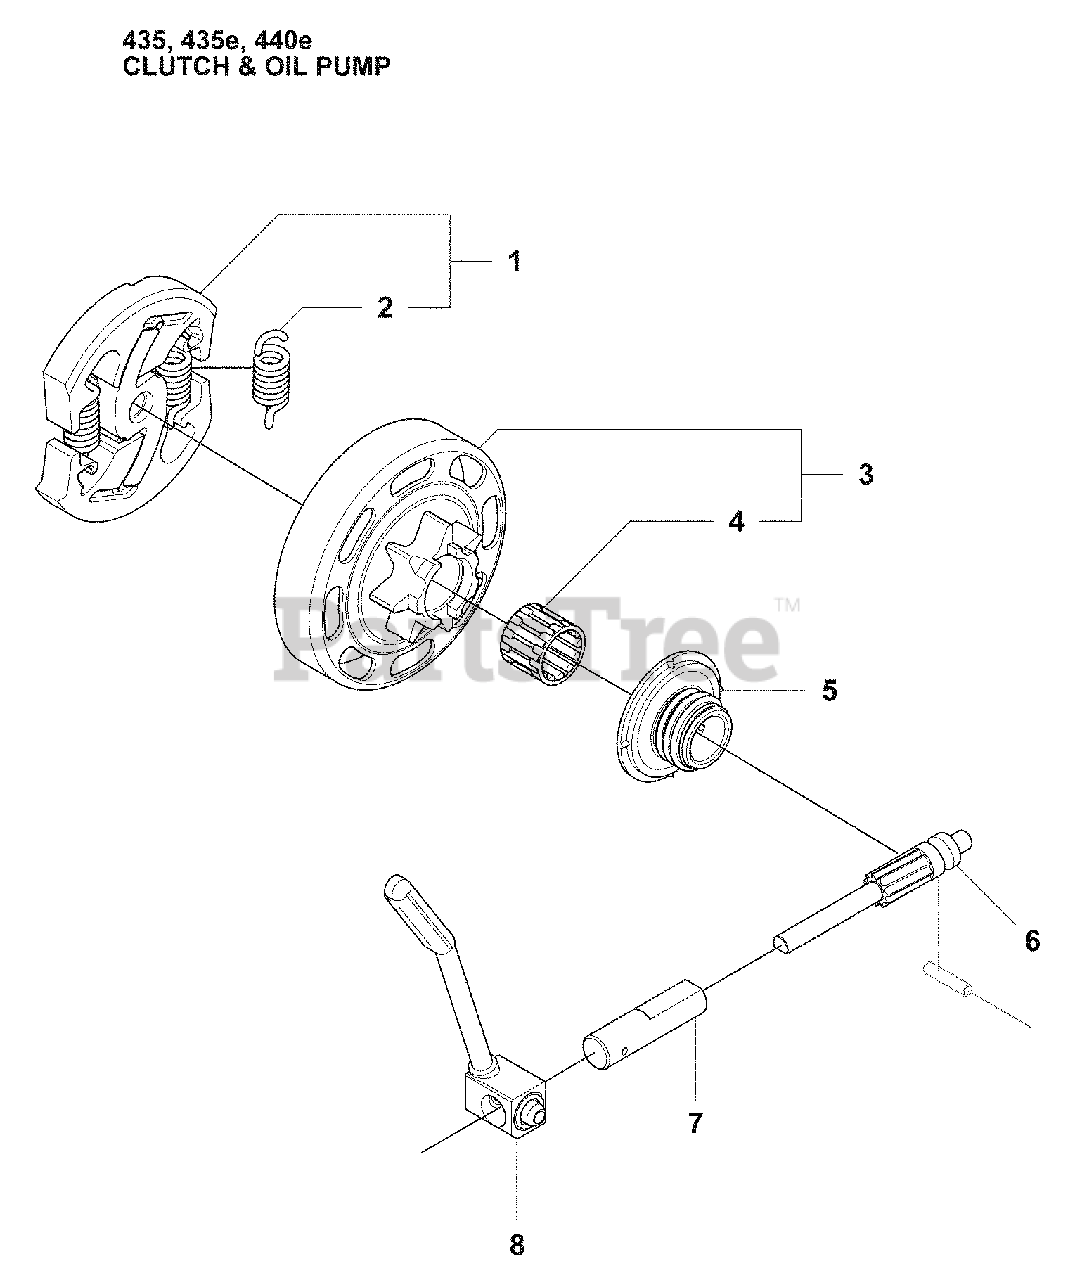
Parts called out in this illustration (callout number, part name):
1	Clutch Assembly
2	Clutch Spring
3	Clutch Drum Assembly
4	Support Bushing
5	Worm Gear Assembly
6	Piston Pump
7	Cylinder Pump
8	Oil Hose
